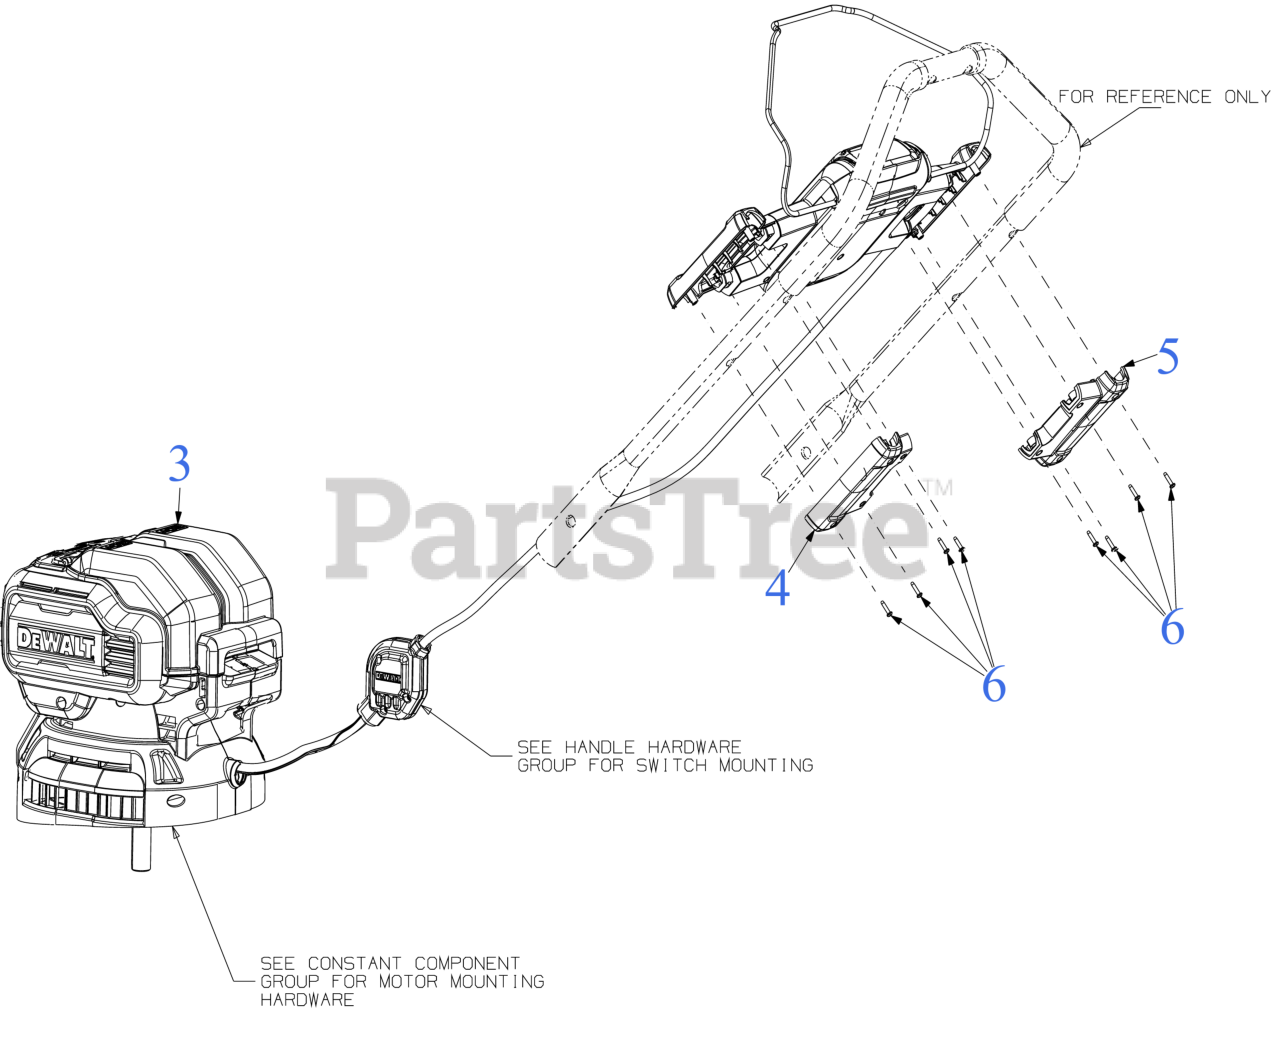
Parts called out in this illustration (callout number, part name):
4	HANDLE PANEL COVER (REAR) (LH) (YELLOW)
5	HANDLE PANEL COVER (REAR) (RH) (YELLOW)
6	SCREW-TAP PLASTIC #6-19 x 0.63
